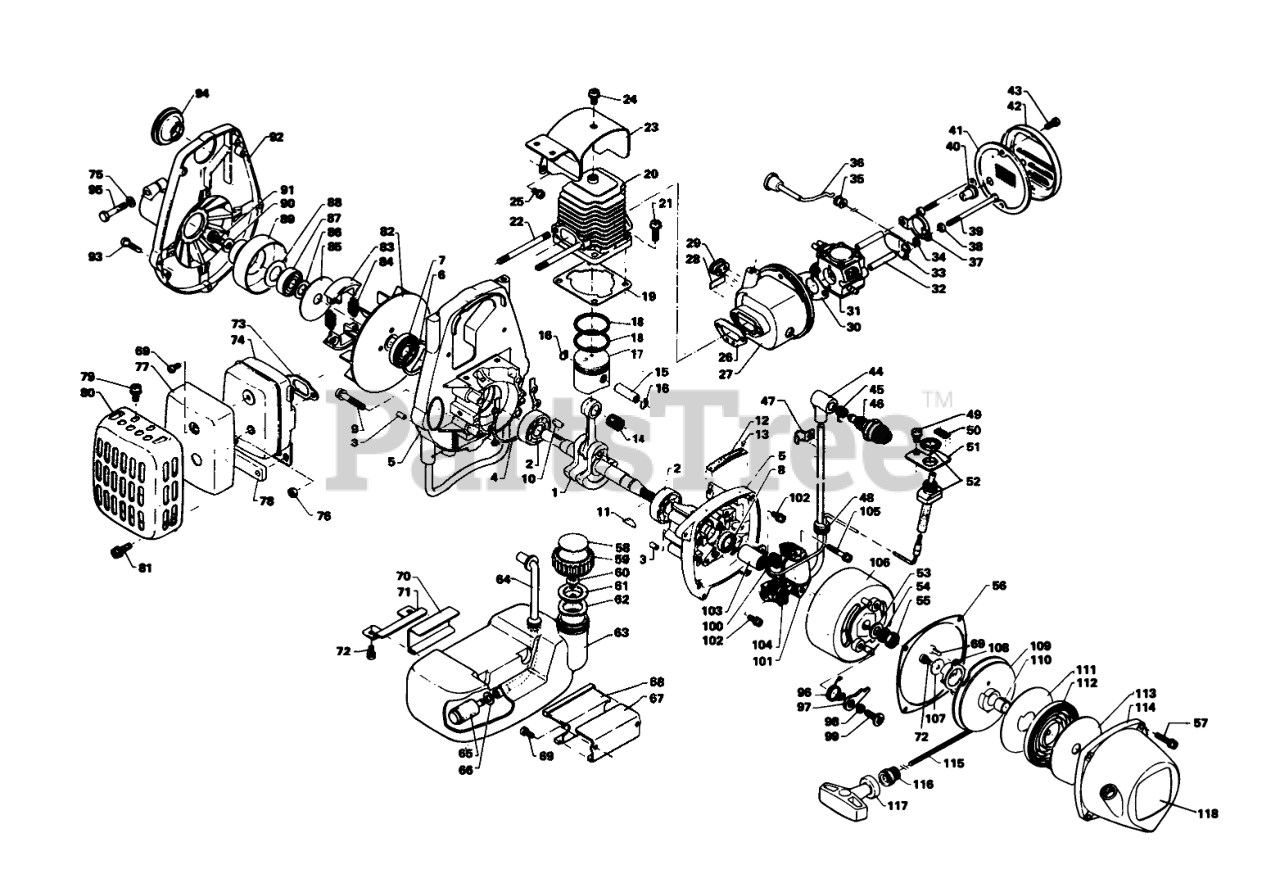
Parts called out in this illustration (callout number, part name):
1	Crankshaft Assembly
2	Bearing
3	Knockpin
4	Gasket, Crankcase
5	Crankcase Set
6	Circlip
7	Oilseal
8	Oilseal
9	Screw
10	Woodruff Key
11	Woodruff Key
12	Model Plate
13	Rivet
14	Needle Bearing
15	Piston Pin
16	Circlip, Piston Pin
17	Piston
18	PISTON RING
19	Gasket, Cylinder Base
20	Cylinder
21	Screw
22	Stud Bolt
23	Cylinder Cover
24	Screw
25	Screw
26	GASKET
27	Carburetor Case
28	Decal, Caution
29	Grommet
30	Gasket
31	Carburetor Assembly
32	Carburetor Spacer
33	Choke Shutter
34	Spacer
35	Rubber Grommet, Choke Rod
36	Choke Rod
37	Plate
38	Spacer, Carburetor
40	Grommet
41	Air Filter
42	Cover, Air Cleaner
43	Screw
44	Cap-Spark Plug
45	Coil Spring-Plug Cap
46	Spark Plug
47	Clamp
48	Grommet
49	Screw
50	Decal, Stop
51	Bracket, Switch
52	Switch
53	Washer
54	Spring Washer
56	Gasket, Starter Case
57	SCREW
58	Decal, Fuel
59	Cap-Fuel Tank
60	Check Valve
61	Holder, Check Valve
62	Gasket, Fuel Tank Cap
63	Fuel Tank
64	Fuel Pipe
65	Fuel Strainer
66	Washer
67	Bracket, Fuel Tank
68	Cushion
69	Screw
70	Cushion
71	Bracket, Fuel Tank
72	Screw
73	Gasket, Muffler
74	Muffler
75	WASHER
77	Insulator
78	Spacer
79	SCREW
80	Muffler Cover
81	Screw
83	CLUTCH SHOE
84	CLUTCH SPRING
85	Side Plate
86	Spacer
87	Ball Bearing
88	Spacer
89	Clutch Drum
90	Washer
92	Fan Cover
93	Screw
94	Boot, Plug Cap
96	Spring, Ratchet
97	Ratchet
98	RATCHET SPACER
99	Screw
100	Oiler
101	IGNITION COIL
102	SCREW
103	CONDENSER
104	CONTACT BREAKER SET
105	Screw
106	Flywheel
107	Washer
108	Pawl Catcher
109	Recoil Drum
110	Bushing, Recoil Drum
111	Side Plate, Inner
112	REWIND SPRING
113	Side Plate, Outer
114	Starter Case
115	Starter Rope
116	Rope Guide
117	Starter Handle
118	Decal, 2100
